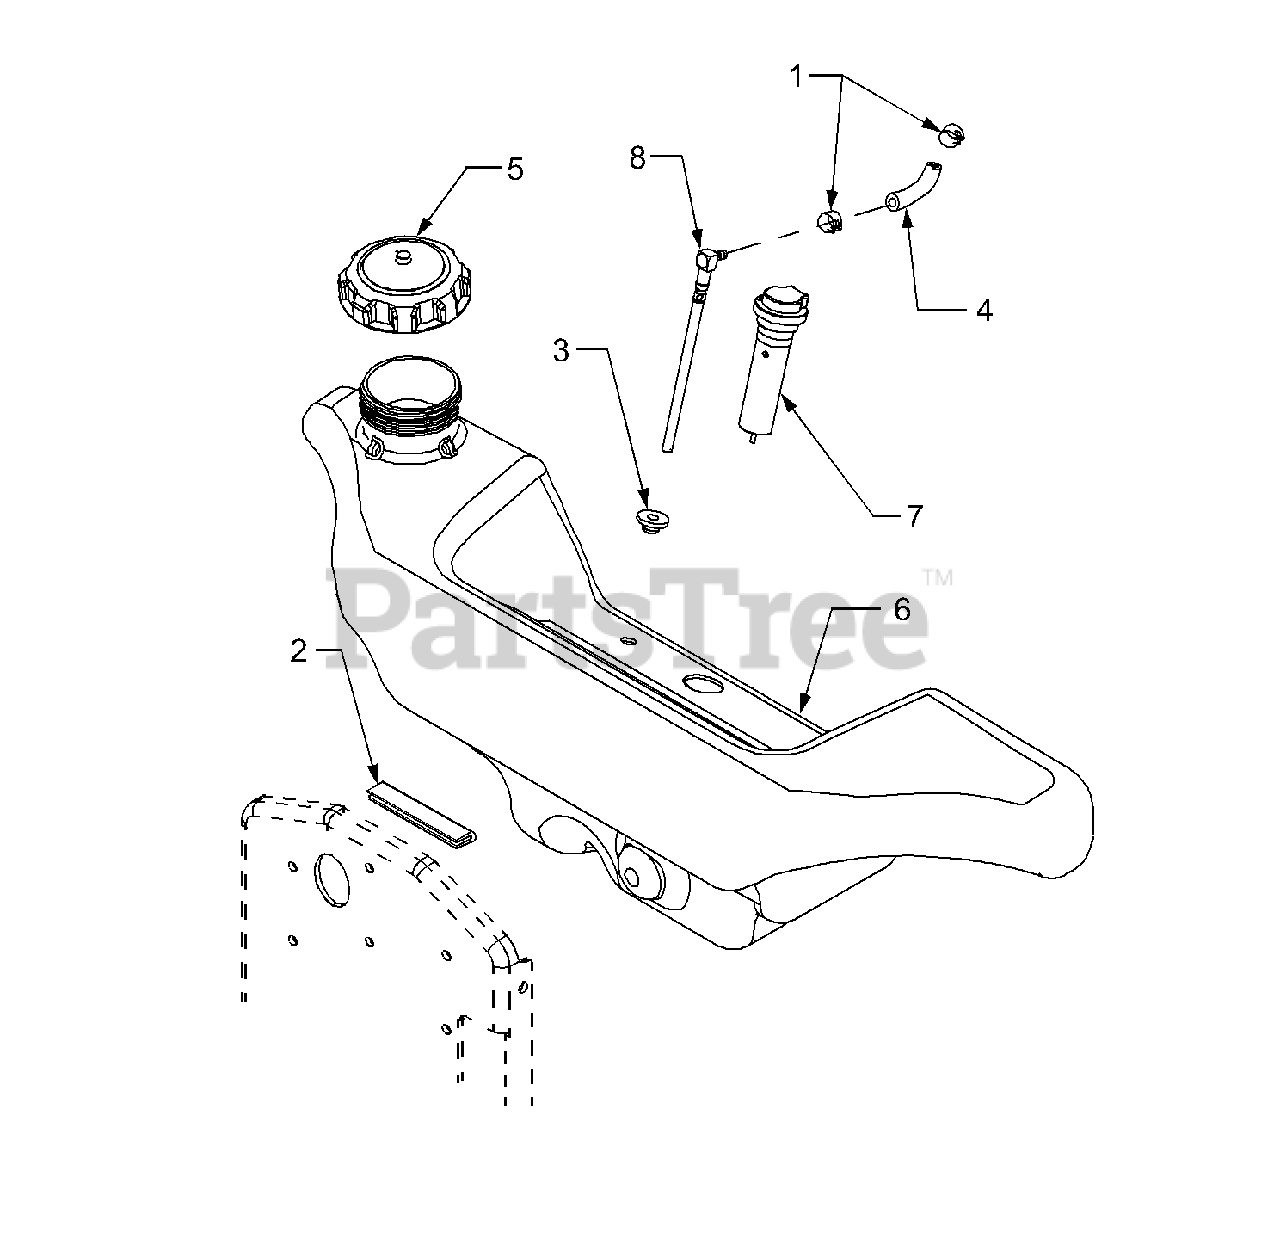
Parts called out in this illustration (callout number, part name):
1	Clamp, Hose
2	Trim, Tank Protector
3	Bushing, Rubber
4	Fuel Line
5	Cap, Fuel
6	Tank, Fuel, 4.5 Gallon
7	Sensor, Low Fuel
8	Fitting, Fuel Pickup
